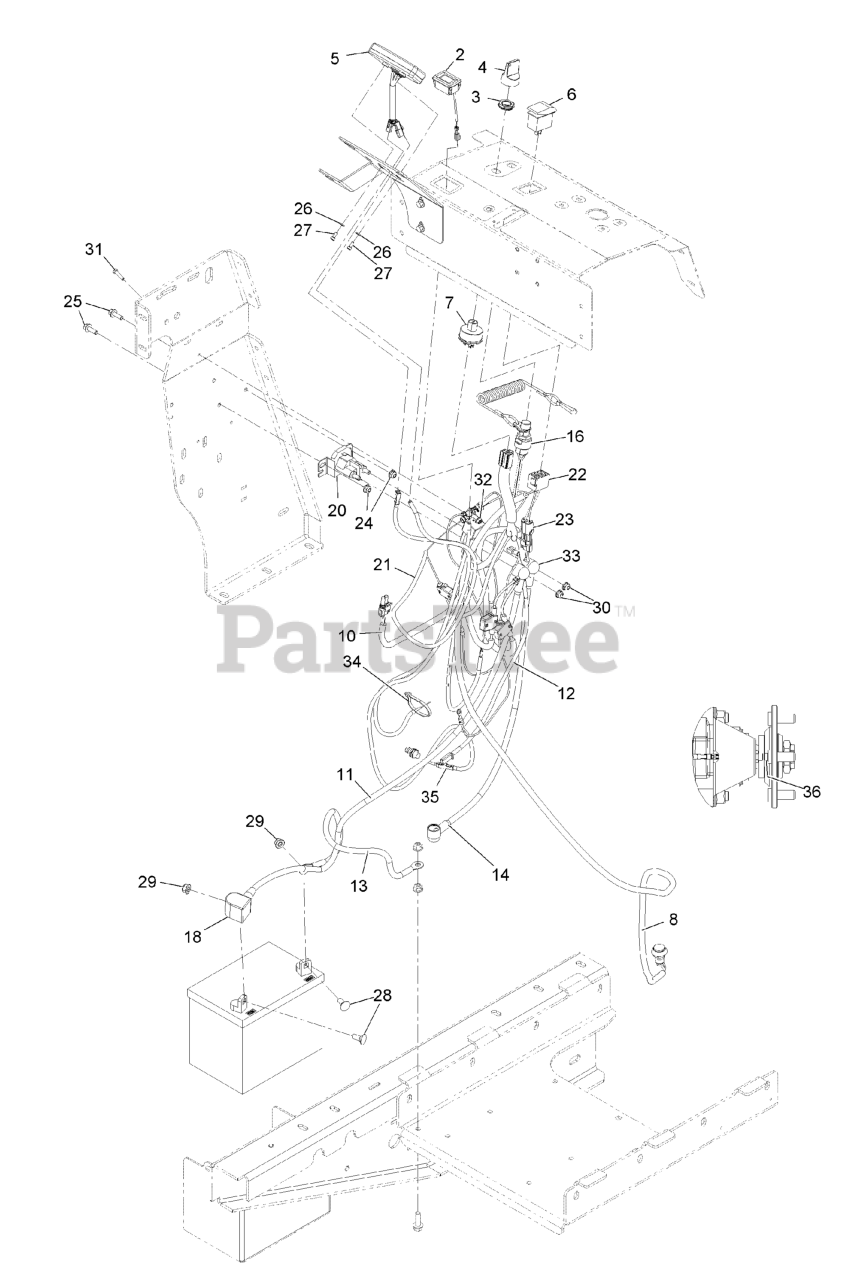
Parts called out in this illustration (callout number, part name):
2	METER-TACH/HOUR
3	NUT-SWITCH, KEY
4	KEY-UMBRELLA
5	HEAD ONLY, STRIKER
6	SWITCH-ROCKER
7	SWITCH-IGNITION
8	Switch-Push Button
10	Harness, Main
11	CABLE-POSITIVE
12	Wire-Solenoid
13	CABLE-GROUND
14	CABLE-POSITIVE
16	SWITCH-OP
18	Insulator-Battery
20	Solenoid-Starter
21	HARNESS-STRIKER
22	CONNECTOR-CARLING, 8F
23	Connector-Wp,2M
24	Nut-Hex Flange
25	Screw-HHF
26	WASHER-FLAT
27	SCREW-HSH
28	SCREW-CARR
29	Nut-Hex Flange
31	SCREW-HH
32	Nut-Hex Flange
33	INSULATOR-SOLENOID
34	TIE-CABLE
35	Cable-Trail Tech, Sensor
36	MAGNET, SPEEDOMETER
